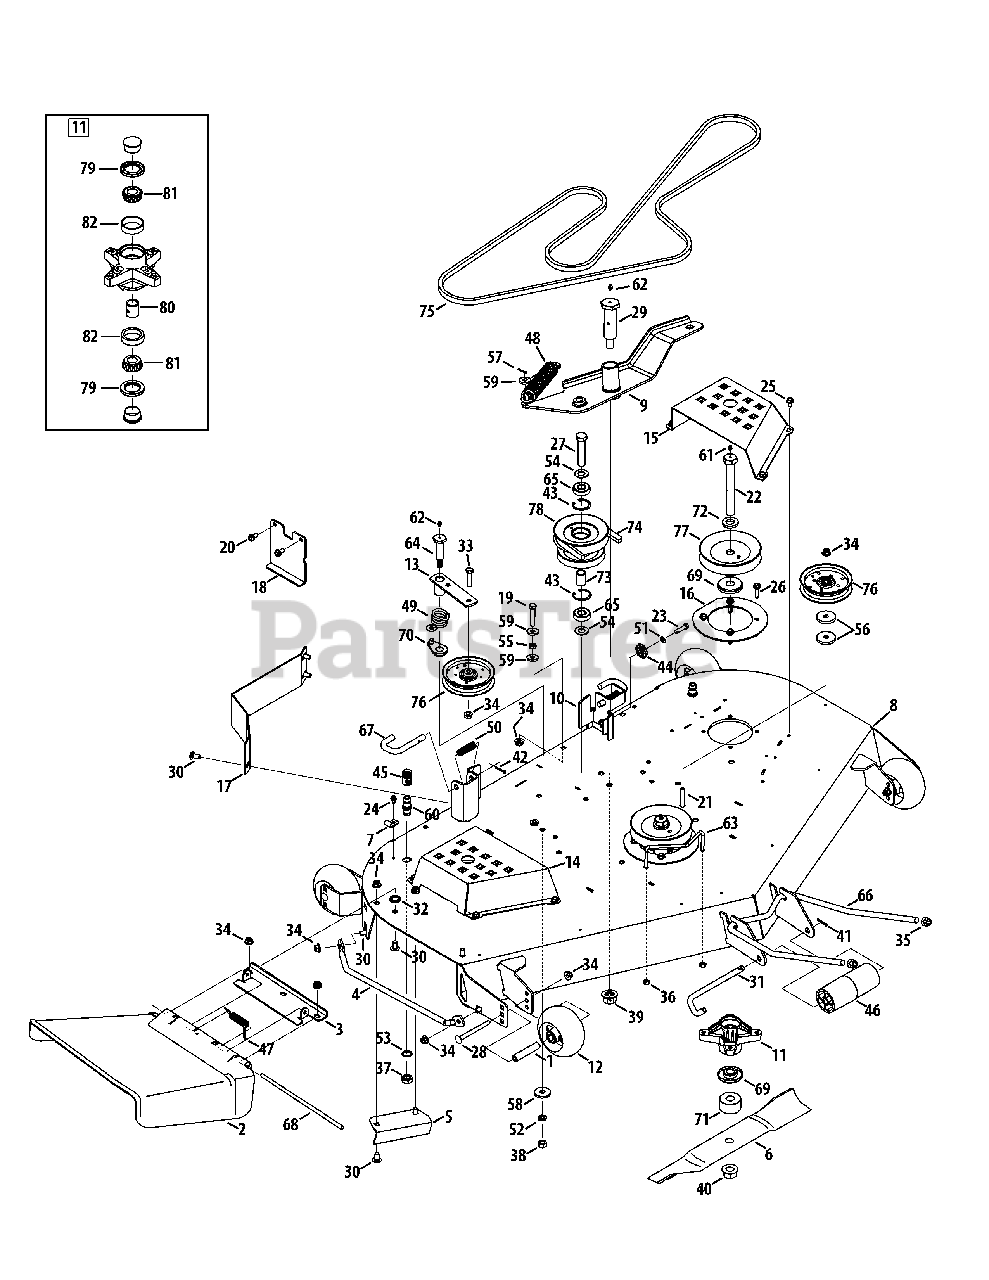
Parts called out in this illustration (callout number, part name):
1	Spacer, .390 x .620 x 3.04"
2	Chute Deflector
3	Chute Deflector Bracket
4	Finger Guard
5	Micor Chute Baffle
6	Hi-Lift Blade, 19"
7	Hook Retainer Bracket
11	Spindle Assembly
12	Wheel, 5.0"
16	Spindle Reinforcement Plate
17	Baffle
18	Up-Stop Bracket
19	Hex Screw, 3/8 x 16 x 1.75"
20	Hex Washer Screw, 5/16-18 x .750"
21	Carriage Bolt, 3/8-16 x 2.50"
22	Hex Screw, 3/4-16 x 6.00"
23	Hex Screw, 5/16-18 x 1.25"
24	Hex Washer Screw, 1/4-20 x .500"
25	Hex Washer Screw, 5/16-18 x .625"
26	Hex Washer Screw, 5/16-18 x 1.50"
27	Hex Screw, 5/8-18 x 3.00"
28	Carriage Screw, 3/8-16 x 4.00"
29	Shoulder Screw, 1.0 x 3.00"
30	Carriage Bolt, 3/8-16 x 1.00"
31	Roller Pin, 1/2 x 7.31"
32	Push Nut, 3/8"
33	Hex Screw, 3/8-16 x 1.50"
34	Flange Lock Nut, 3/8-16"
35	Flex Lock Nut, 1/2-13"
36	Hex Lock Nut, 1/4-20"
37	Hex Nut, M16-1.5"
38	Hex Nut, 7/16-14"
39	Flange Lock Nut, 5/8-18"
40	Flange Lock Nut, 3/4-16"
41	Cotter Pin, 3/32 x 1.25"
42	Cotter Pin, 5/32 x 1.25"
43	Retainer Ring
44	Deck Adjustment Gear
45	Water Nozzle Adapter
46	Front Roller
47	Torsion Spring, 180 x .639 x 2.16 x .12"
48	Extension Spring, 1.25 x 6.9"
49	Idler Torsion Spring, 1.10 x 1.3"
50	Compression Spring, .66 x 1.8"
51	Lock Washer, 5/16"
52	Lock Washer, 7/16"
53	Lock Washer, 5/8"
54	Flat Washer, .650 x 1.250 x .075"
55	Jam Nut, 3/8-16"
56	Flat Washer, .4375 x 1.75 x .25"
57	Cotter Pin, 3/32 x .750"
58	Flat Washer, .45 x 1.5 x .172"
59	Falt Washer, .385 x 1.00 x .135"
60	Deck Water Nozzle
61	Grease Fitting, 1/4-28 x 3/16"
62	Drive Lube Fitting, 3/16"
63	Belt Drive Guard
64	Shoulder Screw, 7/16-14 x .687 x 2.443"
65	Ball Bearing, .625 x 40 x 12"
66	Front Hanger Rod
67	Mower Support Pin
68	Chute Deflector Rod
69	Spindle Deck Spacer
70	Retainer Spring
71	Spindle Spacer, .760 x 2.0 x 1.10"
72	Spacer, .812 x .218"
73	Spacer, .88 x .635 x 1.25"
76	Idler Pulley
78	Double Pulley
80	Bearing Spacer, .78 x 1.0 x 1.0425"
81	Cone Bearing, .750"
82	Bearing Cup, .750"
